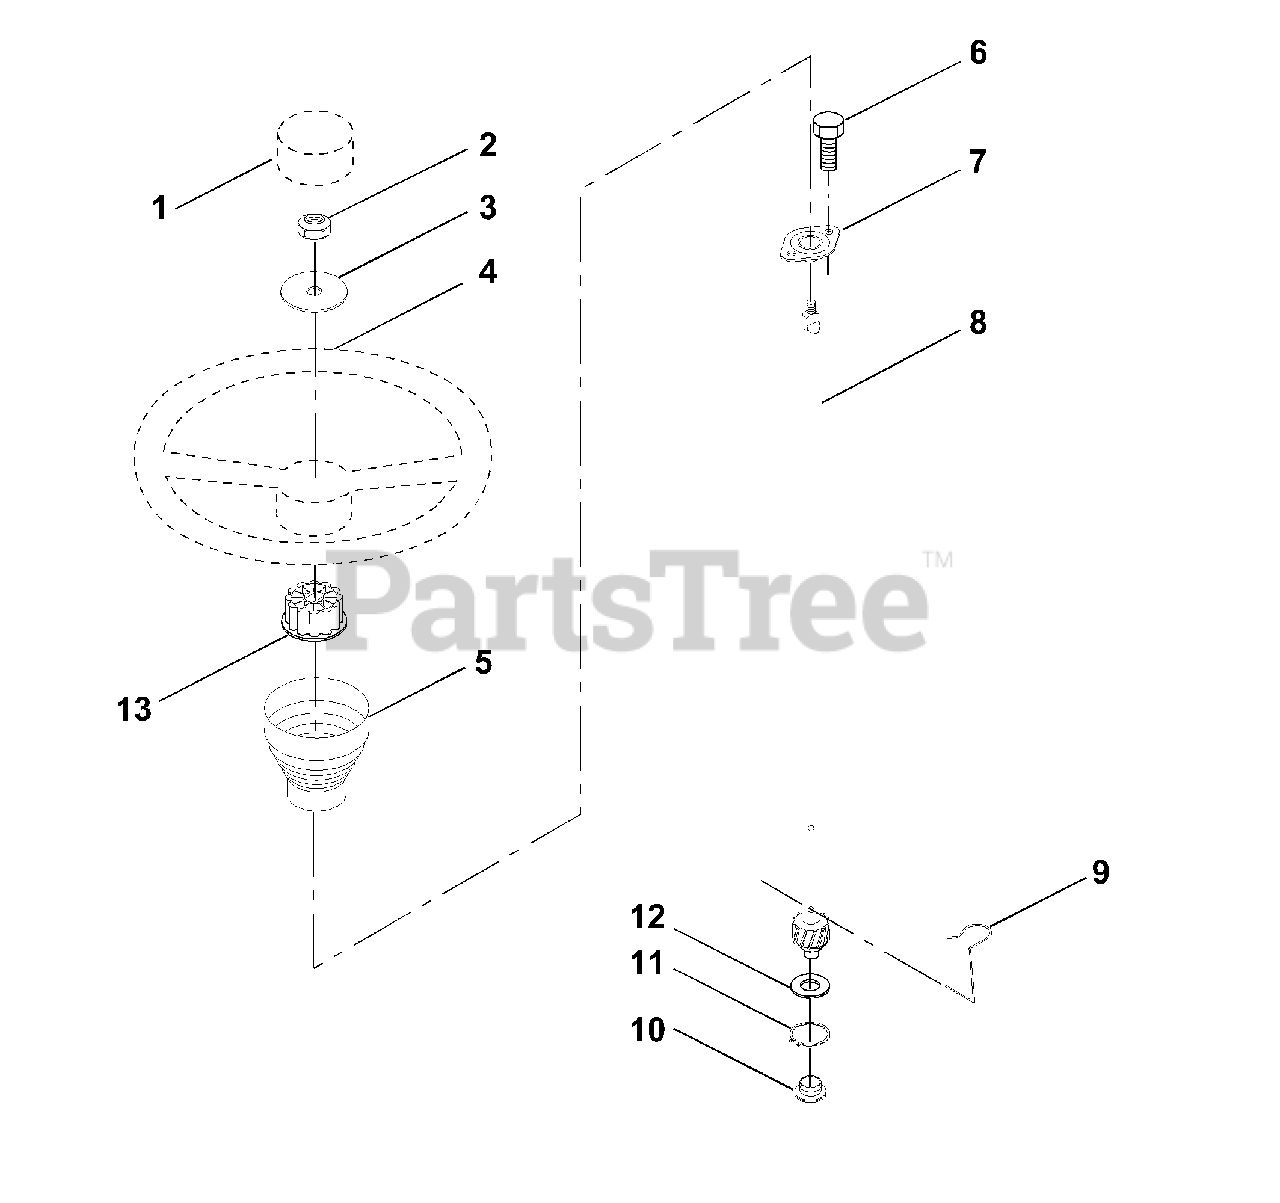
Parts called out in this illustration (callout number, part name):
1	Insert, Wheel, Steering
2	Nut, Lock 3/8-24 UNF
3	Washer 12/32 x 2-3/8 x 8 Ga.
4	Wheel, Steering
5	Sleeve, Steering
6	Screw, Hex #10-16 x 1/2 TY-B
7	Bushing, Steering
8	Shaft, Steering
9	Clip, Steering
10	Bushing, Lower, Steering
11	Ring, Retaining
12	Washer 21/32 x 1 x 16 Ga.
13	Adaptor, Wheel, Steering
